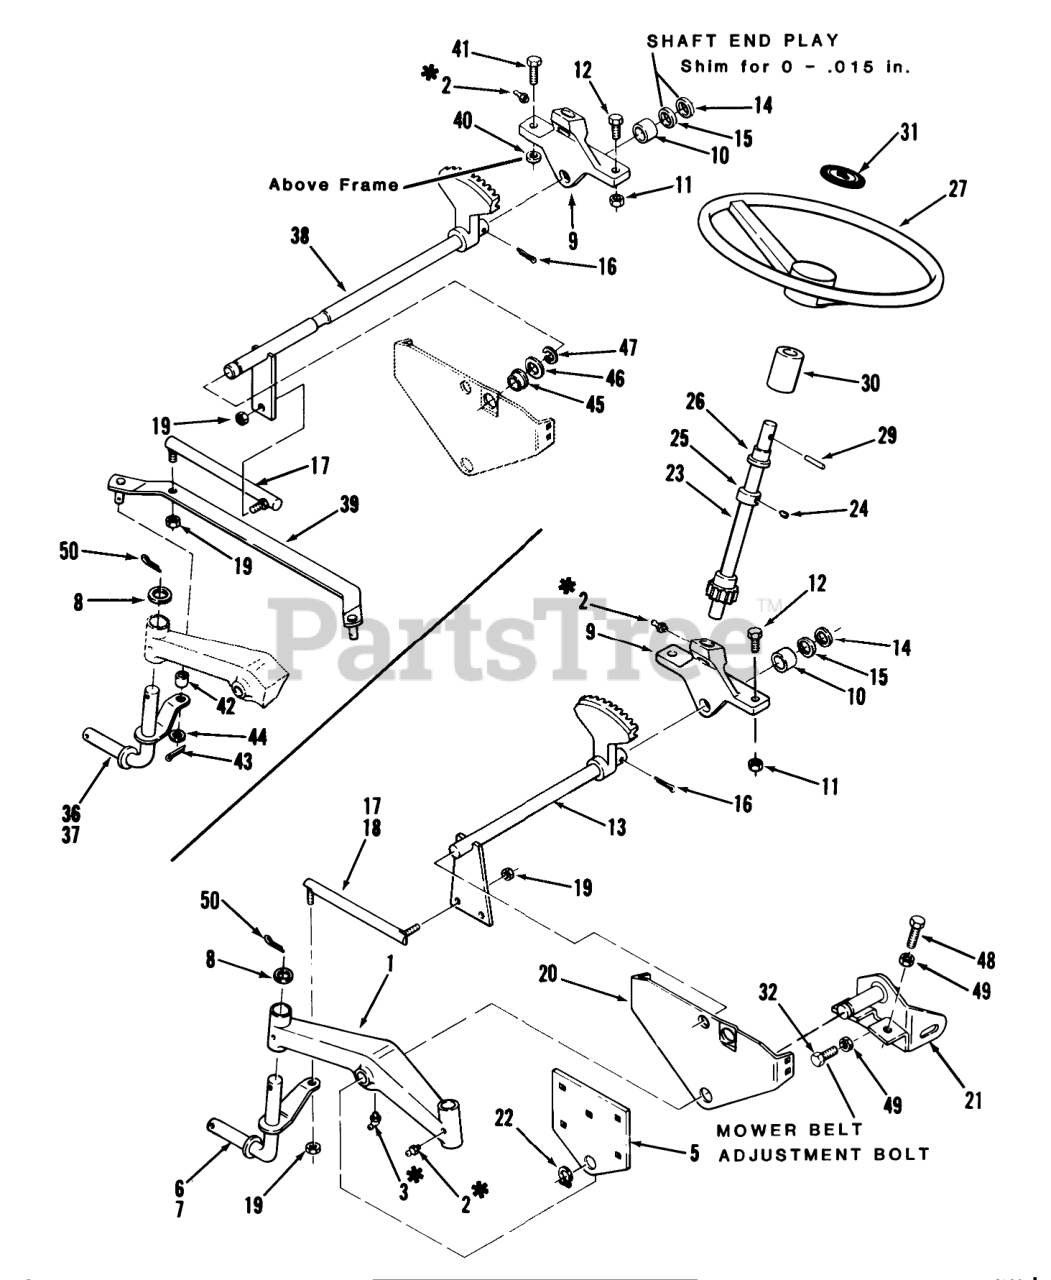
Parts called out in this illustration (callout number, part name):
1	AXLE-FRONT R
2	Zerk
3	FITTING-GREASE
5	PLATE-FRONT AXLE R
6	Front Spindle RH B-115 Only
7	Front Spindle LH B-115 Only
8	WASHER
9	Support
10	BEARING-BRONZE
11	Nut
12	BOLT
13	ASSY-STRG SHFT LO R
14	WASHER-SHIM
15	WASHER
16	PIN-4
17	25LL JOINT ASSY R R
18	BALL JOINT ASSY L R
19	NUT-6
20	Support Front Axle
21	ASSY-FRONT HANGER R
22	Snap Ring
23	ASSY-STRG SHFT-UP R
24	SCREW-SET
25	Collar
26	BEARING
27	STEERING WH 13" SOFT
29	Pin-Roll
30	COLLAR
31	STEERING WHEEL INSE
32	SCREW-HH
36	Front Spindle RH B-165 Only
37	Front Spindle LH B-165 Only
38	Assy Strg Lower B-165 Only
39	ASSY-TIE ROD R
40	WASHER
41	Bolt
42	SPACER
44	WASHER
45	BUSHING
46	WASHER SPECIAL
47	Ring
48	Bolt
49	Nut
50	COTTER PIN-4
